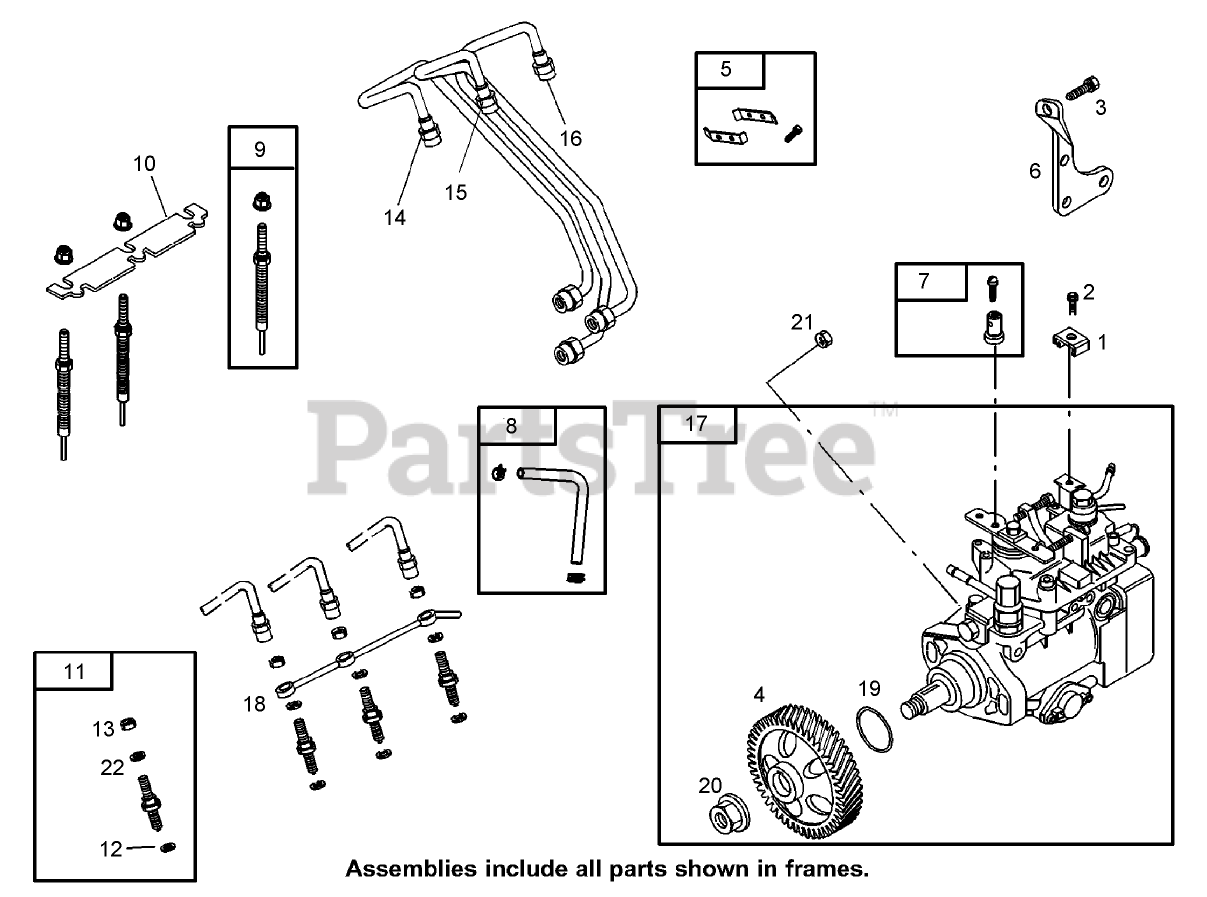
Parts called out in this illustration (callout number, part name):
2	SCREW-HEX
3	SCREW-HEX
4	GEAR-DRIVE
5	CLAMP
6	BRACKET-SUPPORT
7	CLAMP-SWIVEL
8	HOSE / CLAMP ASM
10	STRAP-PLUG, GLOW
11	NOZZLE-INJECTOR
12	SEAT-INJECTOR
14	PIPE-INJECTOR, NO. 1
15	PIPE-INJECTOR, NO. 2
16	PIPE-INJECTOR, NO. 3
17	PUMP-INJECTION
18	PIPE-RETURN, FUEL
19	O-RING
20	NUT-HEX, METRIC
21	NUT-HEX, METRIC
22	SEAT-INJECTOR
